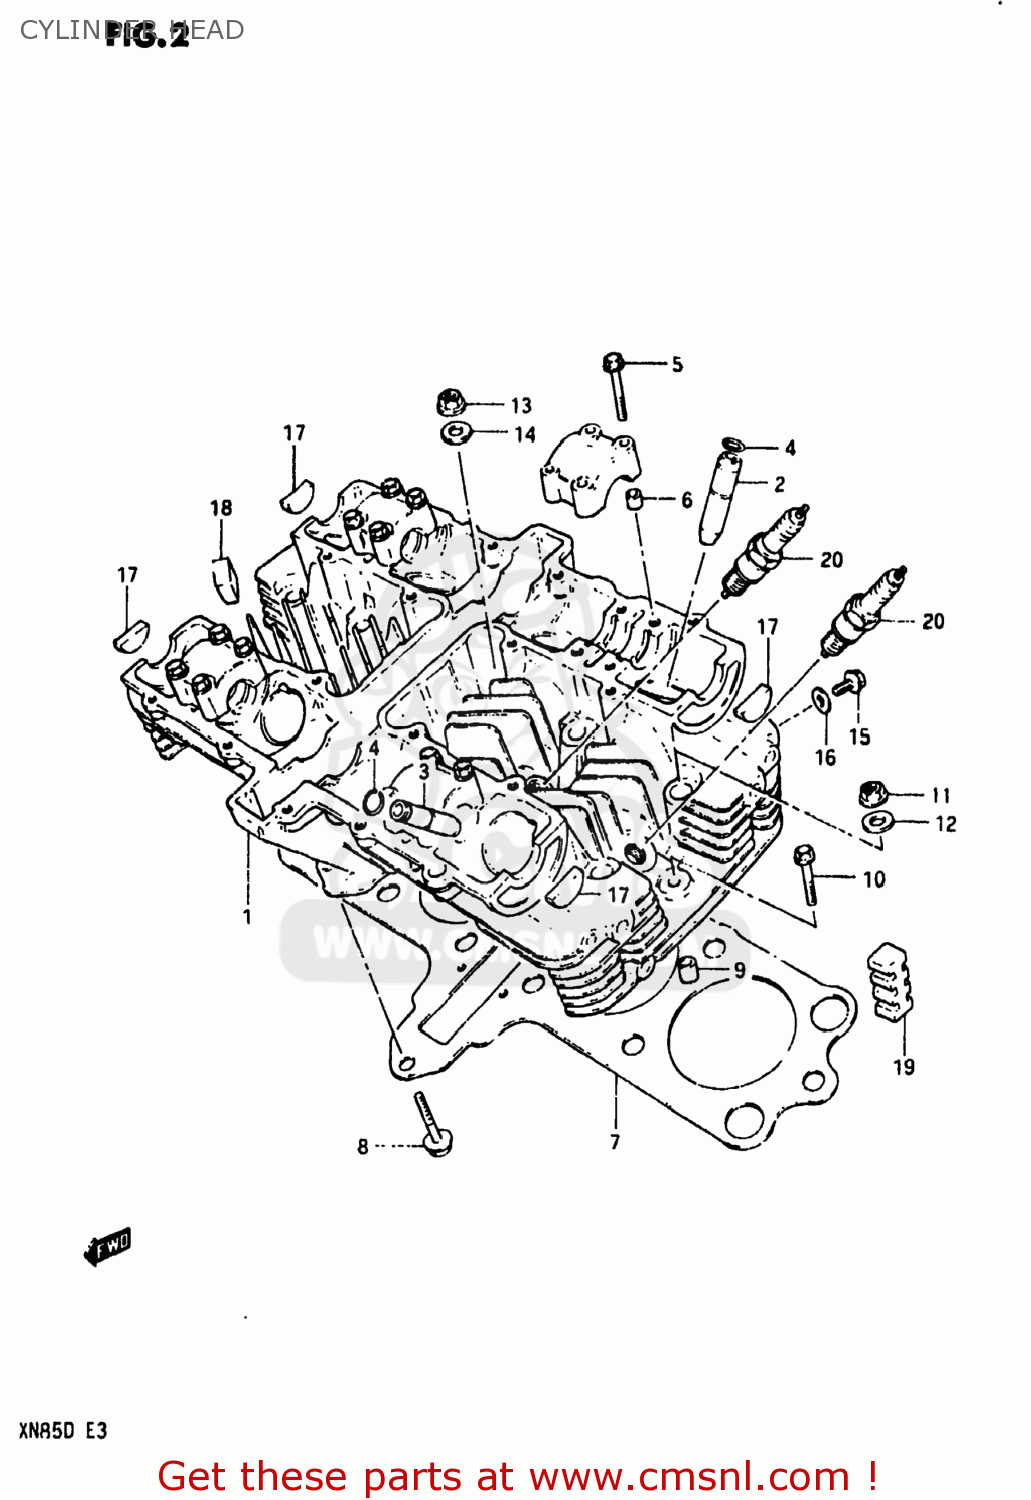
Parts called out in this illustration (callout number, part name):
1	HEAD ASSEMBLY,CYLINDER
2	GUIDE,INTAKE VALVE
3	GUIDE,EXHAUST VALVE
4	RING,SNAP
5	BOLT(6X39)
6	PIN(6.2X8X11)
7	GASKET,CYLINDER HEAD
8	BOLT
9	PIN
10	BOLT,UNDER
11	NUT
12	GASKET 10.5X22X2.0 (NAS)
13	NUT
14	WASHER(10.5X22X2.3)
15	BOLT
16	WASHER
17	PLUG
18	PAD,CYLINDER HEAD
19	PAD,RUBBER N4
20	SPARK PLUG D9EA
